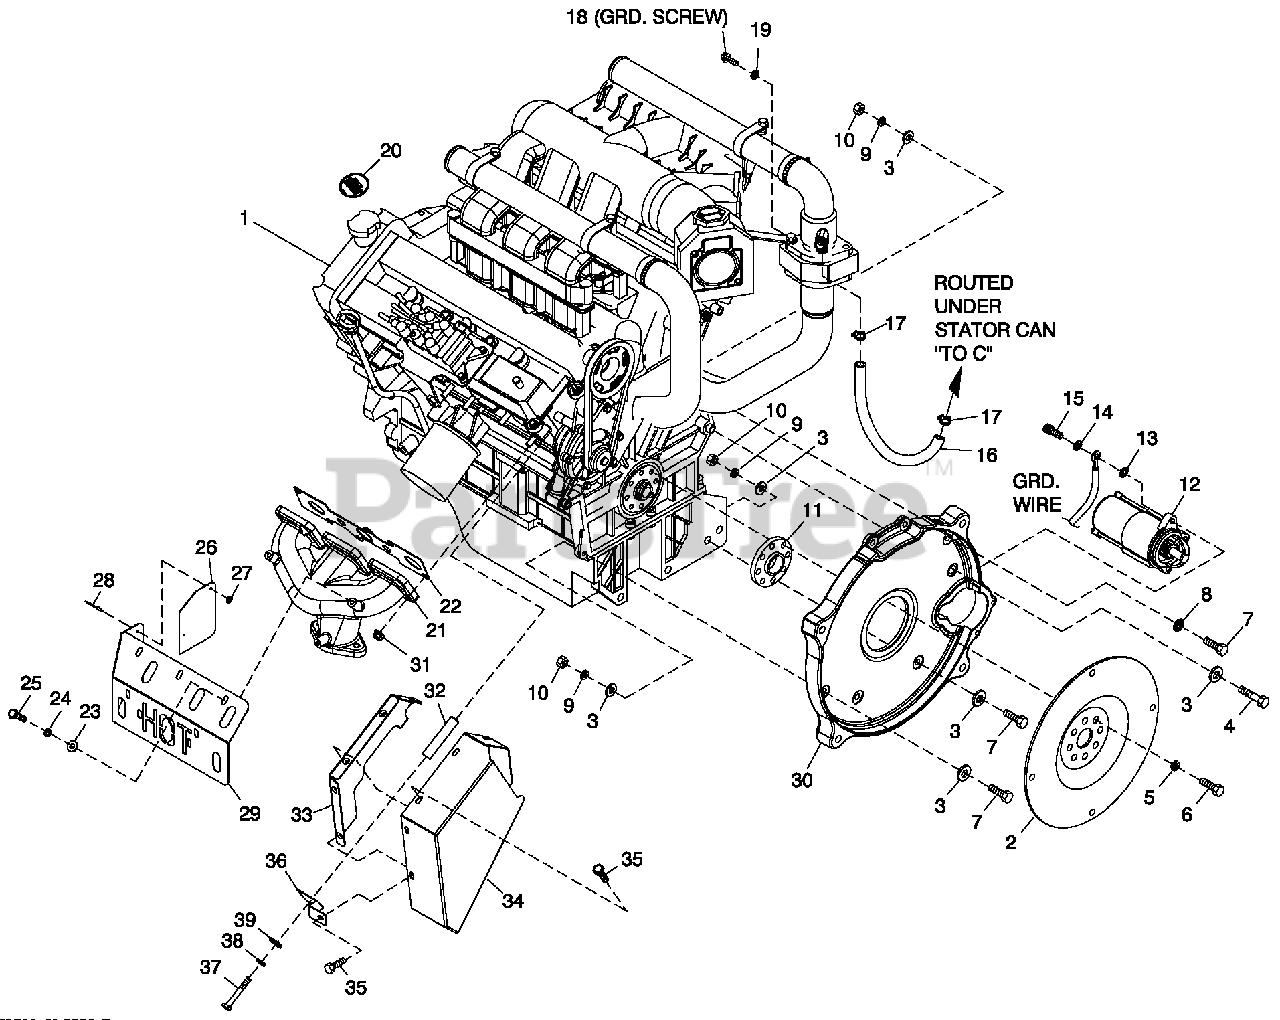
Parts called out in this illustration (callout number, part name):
1	ENGINE 3.0L G3 FWD MAKE
2	FLEX PLATE 2 POLE
3	WASHER FLAT 3/8-M10 ZINC
4	SCREW HHC M10-1.5X 60 G8.8
5	WASHER FLAT .45X1.00
6	SCREW HHC M10-1.0 X 25 G10.9
7	SCREW HHC M10-1.5 X 45 G8.8 FT
8	WASHER SHAKEPROOF EXT 7/16 STL
9	WASHER LOCK M10
10	NUTHEXM10-1.5 G8 YEL CHR
11	SPACER FLEX PLATE
12	STARTER MOTOR 12V
13	WASHER SHAKEPROOF EXT 5/16 STL
14	WASHER LOCK M8-5/16
15	SCREW SHC M8-1.25 X 30 G12.9
16	HOSE COOL 3/4 ID 20R3 (51.5" LG)
17	CLAMP HOSE #10 .56-1.06
18	SCREW HHTT M5-0.8X10BP
19	WASHER LOCK M5
20	DECAL REFER TO OWNERS MANUAL
21	MANIFOLD EXHAUST LH
22	GASKET EXHAUST
23	WASHER FLAT 1/4 SS
24	WASHER LOCK 1/4-M6 SS
25	SCREW HHC 1/4-20 X 1/2 SS
26	REFLECTIVE HEAT SHIELD 3.0L
27	WASHER FLAT M3
28	RIVET POP .125 X .275 SS
29	HEAT SHIELD EXHAUST
30	MACHINING,ENG ADAPTOR 3.0L G3
31	NUT HEX FL WHIZ M8-1.25
32	SPACER .48 X .75 X 2.75 ST/ZNC
33	GUARD, FRONT WATER PUMP
34	GUARD, REAR WATER PUMP
35	SCREW THF M6-1 X 16 N WA Z/JS
36	BRACKET WATERPUMP GUARD
37	SCRW HHC M12-1.75X100 C8.8
38	WASHER LOCK M12
39	WASHER FLAT M12
